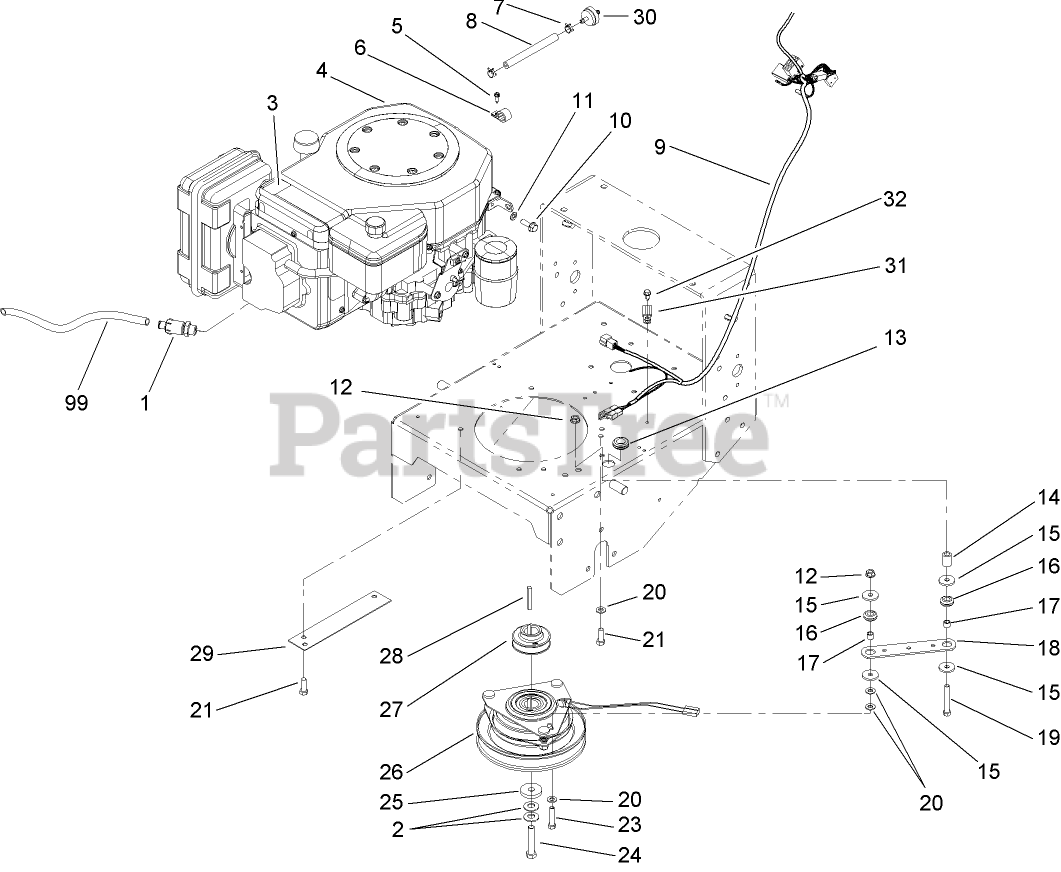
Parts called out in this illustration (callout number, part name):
1	VALVE-DRAIN, OIL
2	WASHER-SPRING
3	DECAL-WARNING
5	SCREW-SHWH
6	CLAMP-CABLE
7	CLAMP-HOSE
8	HOSE-FUEL
9	HARNESS-WIRE
10	SCREW-HHF
11	WASHER-LOCK
12	NUT-HF
13	GROMMET
14	TUBE-RETAINER
15	WASHER
16	GROMMET
17	SPACER
18	STRAP-CLUTCH, BRAKE
19	SCREW-HH
20	WASHER-PLAIN
21	SCREW-HH
23	SCREW-HH
24	SCREW-HH
25	WASHER
26	CLUTCH / BRAKE ASM
27	PULLEY-DRIVE
28	KEY-SQUARE
29	COVER-PULLEY
30	FILTER-FUEL
31	CLAMP-R
32	SCREW
99	HOSE-DRAIN, OIL
